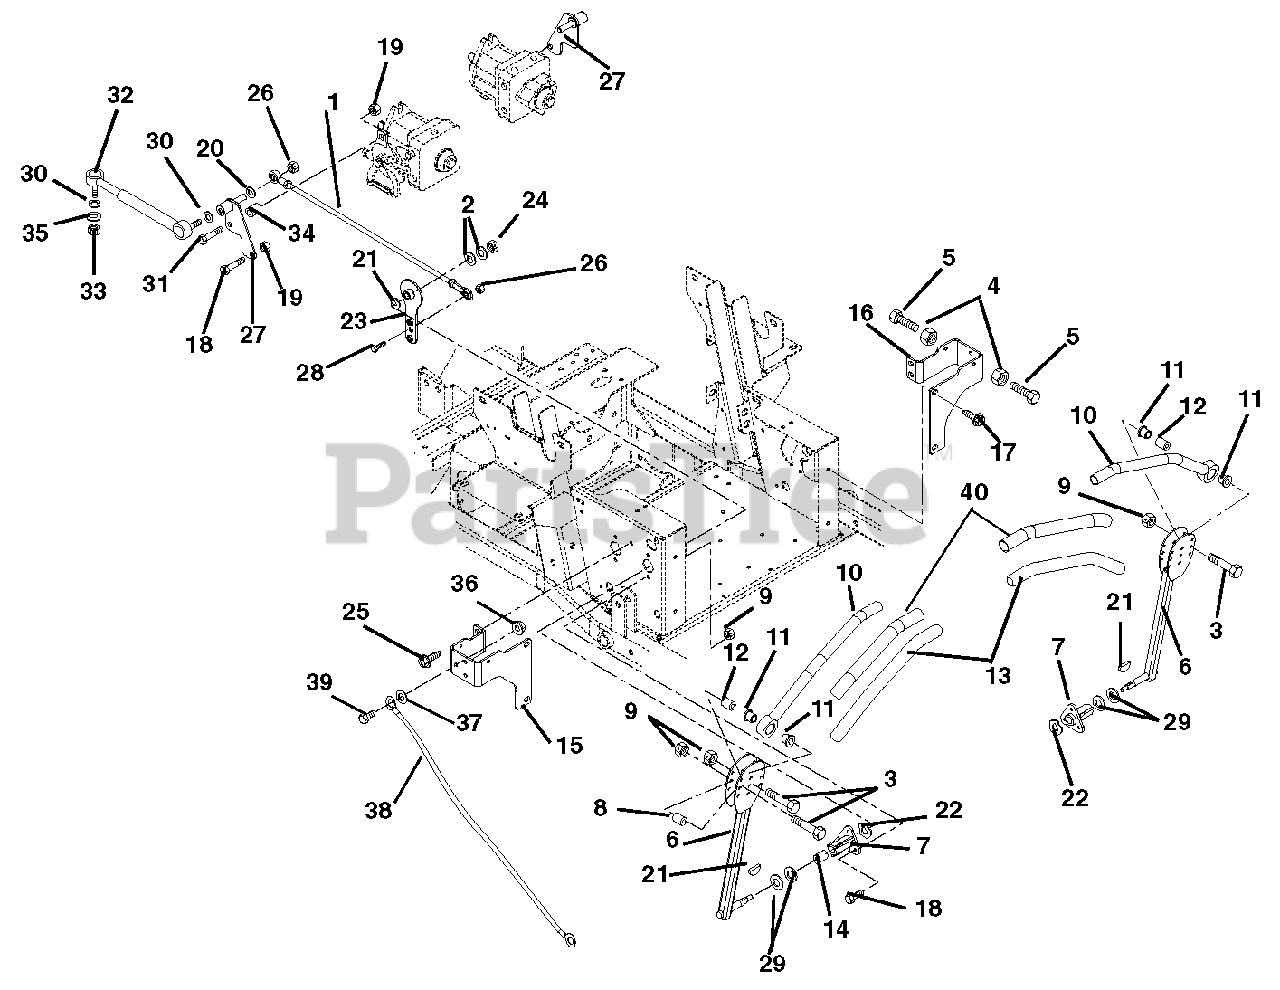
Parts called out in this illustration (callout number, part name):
1	Assembly, Steering Rod .38 Rod x 21.65
2	Washer, Flat Steel .408 x .812 x .065
3	Bolt, Hex .31-18 x 1.75 Grade 5
4	Nut, Hex Jam .375-16
5	Bolt, Hex .375-16 x 1.75
6	Weldment, Control Arm
7	Bushing, Flange
8	Eccentric
9	Nut, Locking Top Flange .31-18
10	Handle Weldment – Left Hand
11	Bushing, Flange Nylon .762 x 1.48 x .44
13	Grip, Handlebar
14	Bushing .625 x .75 x .50
15	Bracket, Stop Right Hand
16	Bracket, Stop Left Hand
17	Screw, Tapping .38-16 x .75 Hex Washer Head
18	Bolt, Hex .31-18 x .75 Grade 5
19	Nut, Locking Top Flange .31-18
20	Washer, Locking .38 x .094 Regular
21	Key, Woodruff .13 x .63
22	Washer, Wave
23	Weldment, Pivot Arm
24	Nut, Locking Top Flange .38-16
25	Screw, Tapping .38-16 x .50 Hex Washer Head
26	Nut, Locking Jam Center .375-16
27	Weldment, Return to Neutral/Damper/Rod End
28	Bolt, Hex .38-16 x 1.25 Grade 5
29	Washer, Flat Steel .63 x 1.005 x .062
30	Washer, Locking .31 x .078
31	Bolt, Hex .31-18 x 1.25 Grade 5
32	Damper, Control
33	Nut, Locking-Nylon M8-1.25
34	Spacer .318 x .43 x .375
35	Washer, Flat Steel .38 x .875 x .083
36	Nut, Locking Top Flange .25-20
37	Washer, Flat Steel .265 x .50 x .087
38	Cable, Seat Prop
39	Bolt, Hex .25-20 x .75 Grade 5
40	Tube, .88ID x 1.00OD x 10.75
